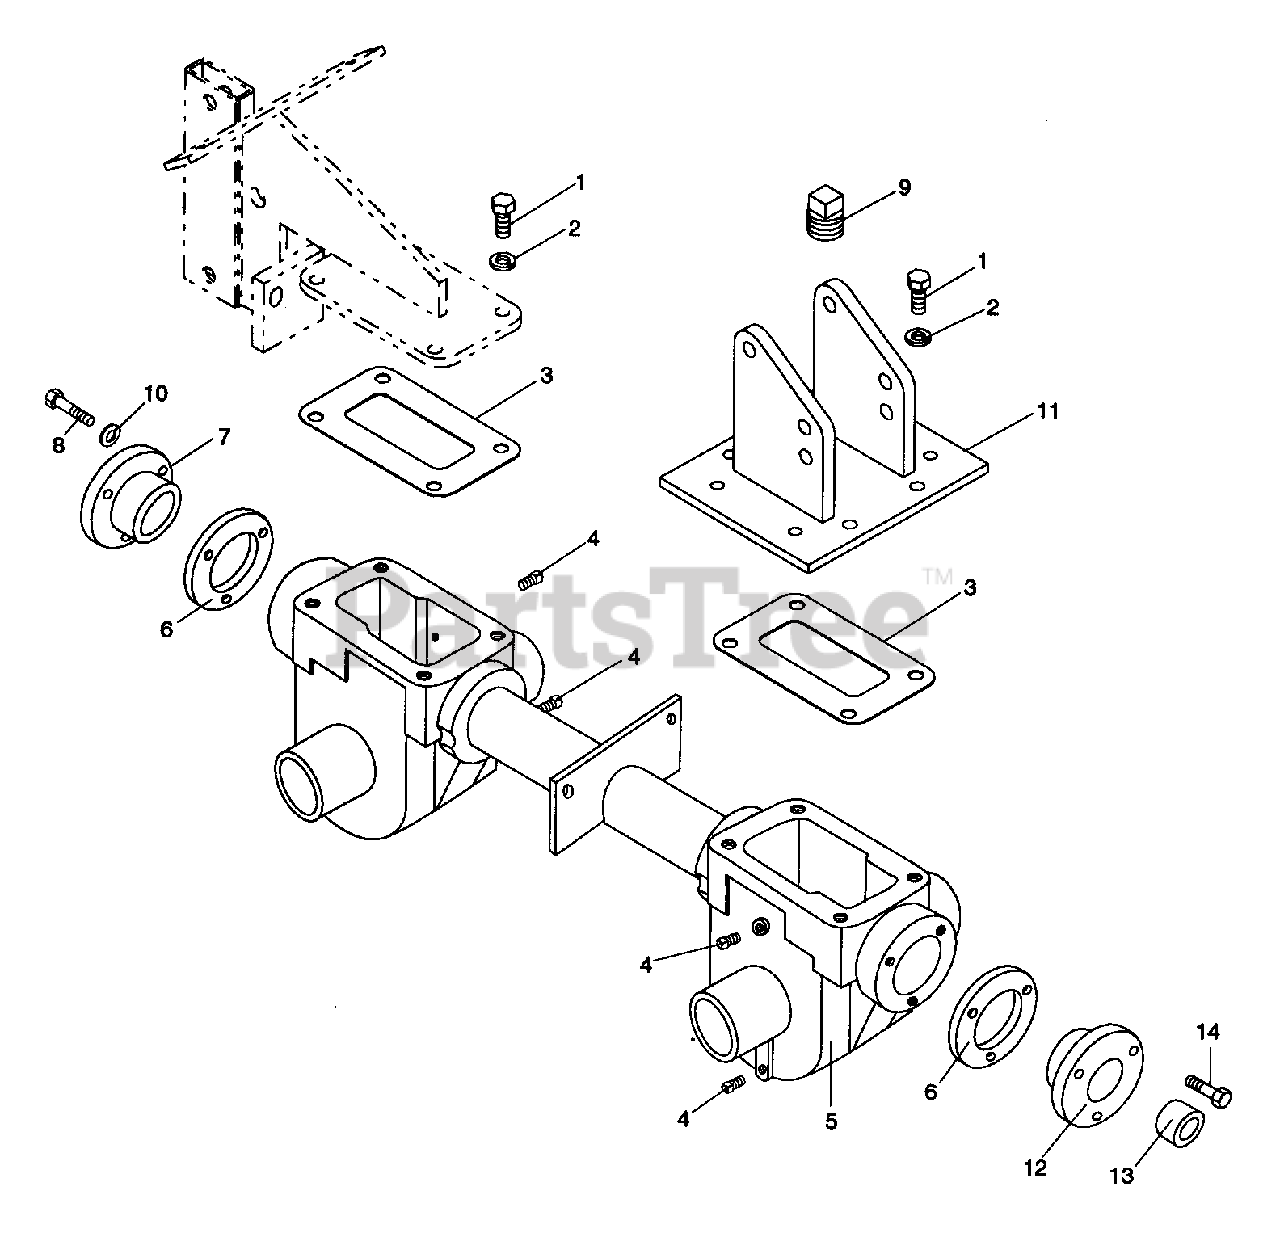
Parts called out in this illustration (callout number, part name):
1	BLT-HEX .31-18X.75 PL GR2
2	WSHR-LK .312X.097 PL HVY
4	PIPE PLUG, 1/4 NPT
5	CASE - TRANSMISSION
6	GASKET, BEARING CAP
7	CAP - REAR BEARING
8	BLT-HEX .25-20X1 HEX SKT HD
9	PIPE PLUG
10	WSHR-LK .250X.077 HVY PL
11	HANDLEBAR MOUNT
12	CAP - FRONT BEARING
13	SEAL TILLER HSG
14	BLT-HEX .25-20X.75 PL GR2
